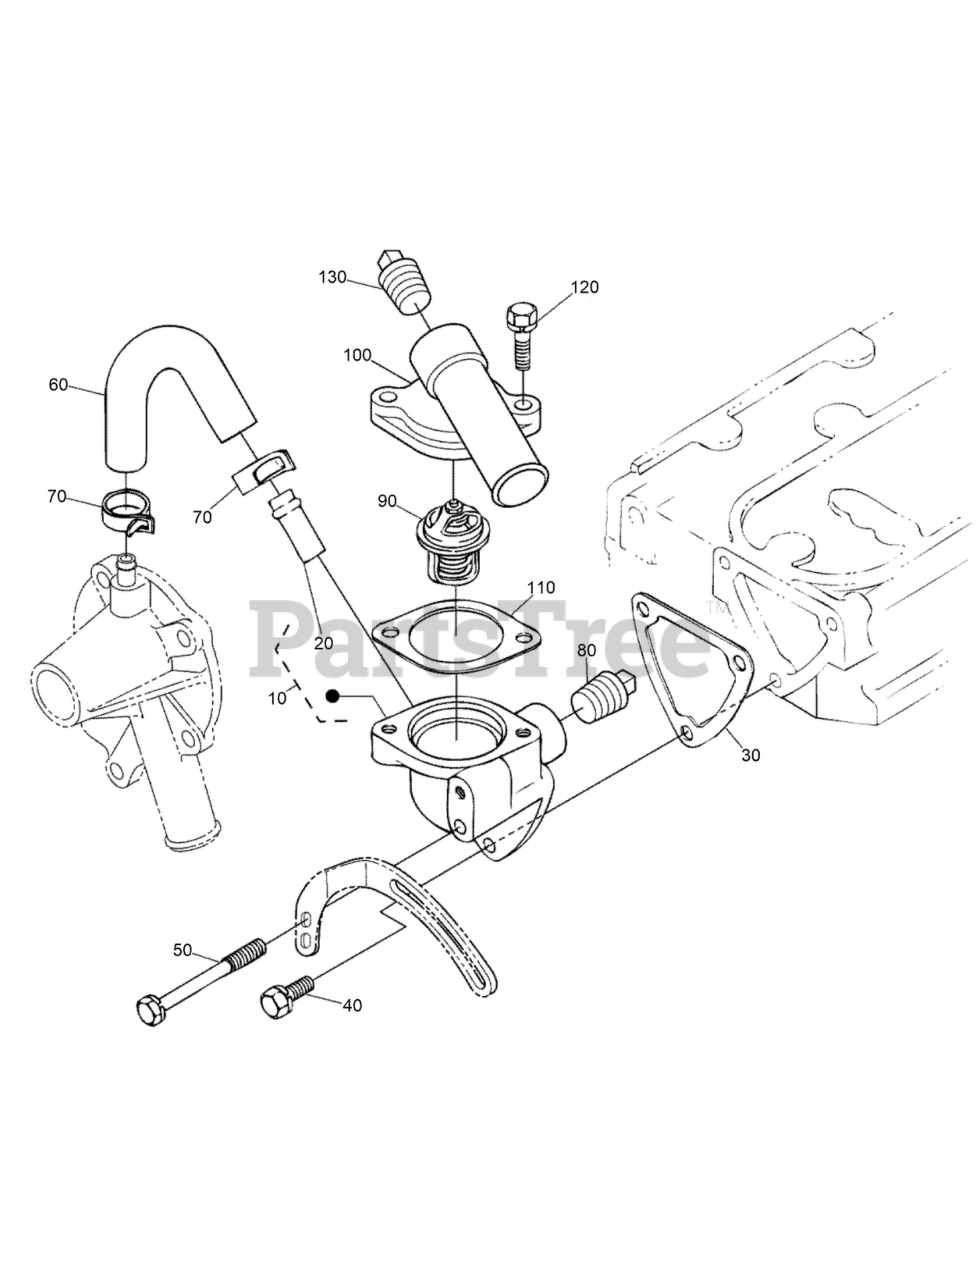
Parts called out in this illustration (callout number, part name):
10	FLANGE,WATER,COMP
20	PIPE-RETURN, WATER
30	GASKET-FLANGE, WATER
60	PIPE,WATER RETURN
70	BAND-PIPE
90	THERMOSTAT ASM
100	COVER,THERMOSTAT
110	GASKET-THERMOSTAT
